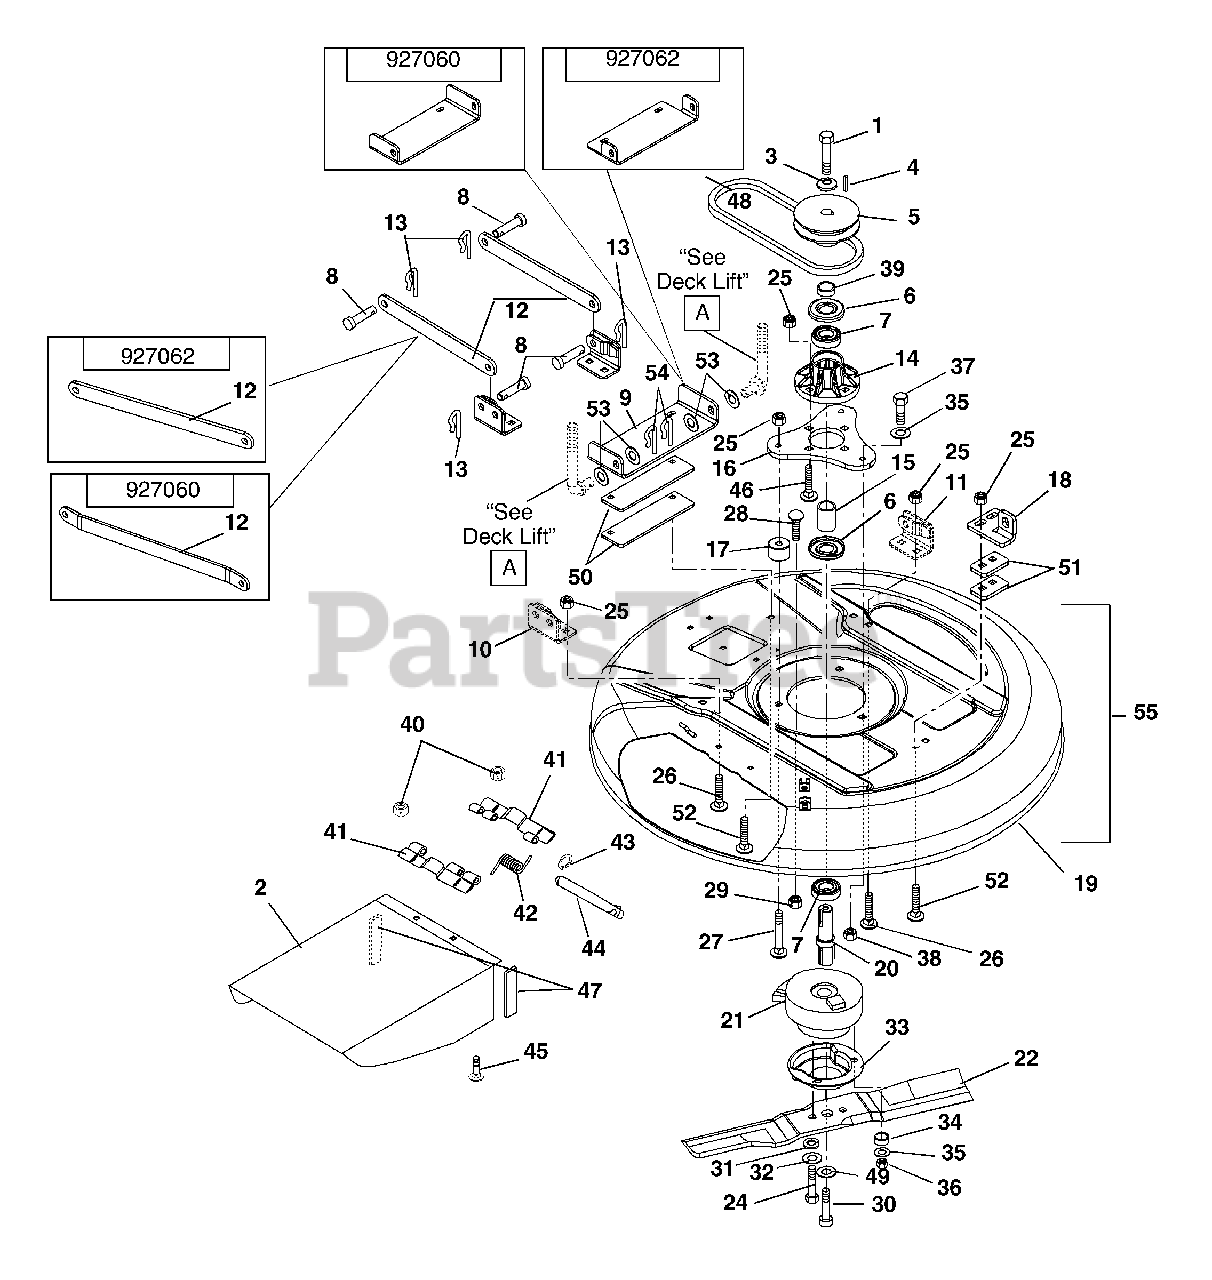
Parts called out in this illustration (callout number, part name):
1	Bolt, Hex .38-16 x 1.00 Grade 8 with Epoxy Patch
2	Chute, 28" (060)
2	Chute, 32" (062)
3	Washer, Cupped Serrated .375
4	Key, Square .25 x .38 x .25
5	Pulley, 28" Deck Input (060)(SN = 101 - 1999)
5	Pulley, 28" Deck Input (060) (SN = 2000 and up)
5	Pulley, 32" Deck Input (062)(SN = 141 - 1499)
5	Pulley, 32" Deck Input (062) (SN = 1500 and up)
6	Bearing, Slinger
7	Bearing, Ball 1.00 x 2.00 x .56
8	Pin, Clevis .494 x 1.00
9	Bracket, Rear Hanger 28" (060)
9	Bracket, Rear Hanger 32" (062)
10	Bracket, Deck Link Right Hand (060)
10	Bracket, Deck Link Right Hand (062)
11	Weldment, Deck Link Right Hand (060)
11	Weldment, Deck Link Left Hand (062)
12	Link-Stabilizer (Right Hand Only) (060)
12	Link Stabilizer (060)
12	Link Stabilizer (062
13	Clip, Spring
14	Assembly, Spindle Housing
15	Spacer, 1.00 x 1.25 x 1.60
16	Spindle, Mount Plate
17	Spacer, Mounting Plate
18	Bracket, Front Lift Hanger (060)
18	Bracket, Front Lift Hanger (062)
19	Deck, 28" (060)
19	Deck, 32" (062)
20	Shaft, 32" Input
21	Clutch Kit (060 SN = 000101 - 1999)
22	Blade, 28" Mower (060)
23	Blade, 32" Mower (062)
24	Bolt, Hex M10 x 1.25 x 30
25	Nut, Locking Top Flange .38-16
26	Bolt, Round Head Square Neck .38-16 x .75 Grade 5
27	Bolt, Round Head Square Neck .38-16 x 2.25 Grade 5
28	Bolt, Round Head Square Neck .31-18 x 1.50 Grade 5
29	Nut, Spin Lock Flange .312-18
30	Bolt, Button Head .50 x 1.25-20
31	Washer, Locking Metric 10 MM
32	Washer, Flat Steel .406 x 1.00 x .188
33	Shield, Debris
34	Bushing, Bronze .75 I.D. x .88 O.D. x .50 Long
35	Washer, Flat Steel .38 x .875 x .083
36	Nut, Locking Nylon .38-16
37	Bolt, Hex .38-16 x 3.00 Grade 5
38	Nut, Flange .375-16
39	Spacer Steel 1.01 x 1.38 x .509
40	Nut, Locking Center .25-20
41	Hinge Plate
42	Spring, Torsion .09 x .37 x .63
43	Ring, Retaining External .312 x .025
45	Bolt, Round Head Square Neck .25-20 x .75 Grade 5
46	Bolt, Round Head Square Neck .38-16 x 1.25 Grade 5
47	Trim Bulk 0125
48	Belt, PTO (060) (SN = 101 - 1999)
48	V-Belt HA, 57.25 (060) (SN = 2000 and up)
48	Belt, PTO (062) (SN = 141 - 1499)
48	V-Belt HA, 63.00 (062) (SN = 1500 and up)
49	Washer, Flat Steel .50 x 1.75 x .187
50	Plate, 32" Deck Spacer
51	Plate, 32 Deck Front Hanger
52	Bolt, Round Head Square Neck .38-16 x 1.25
53	Washer, Flat Steel .518 x 2.00 x .105
54	Pin, Hair External- #11
55	Kit, 28" Deck Assembly Service (060)
55	Kit, 32" Deck Assembly Service (062)
